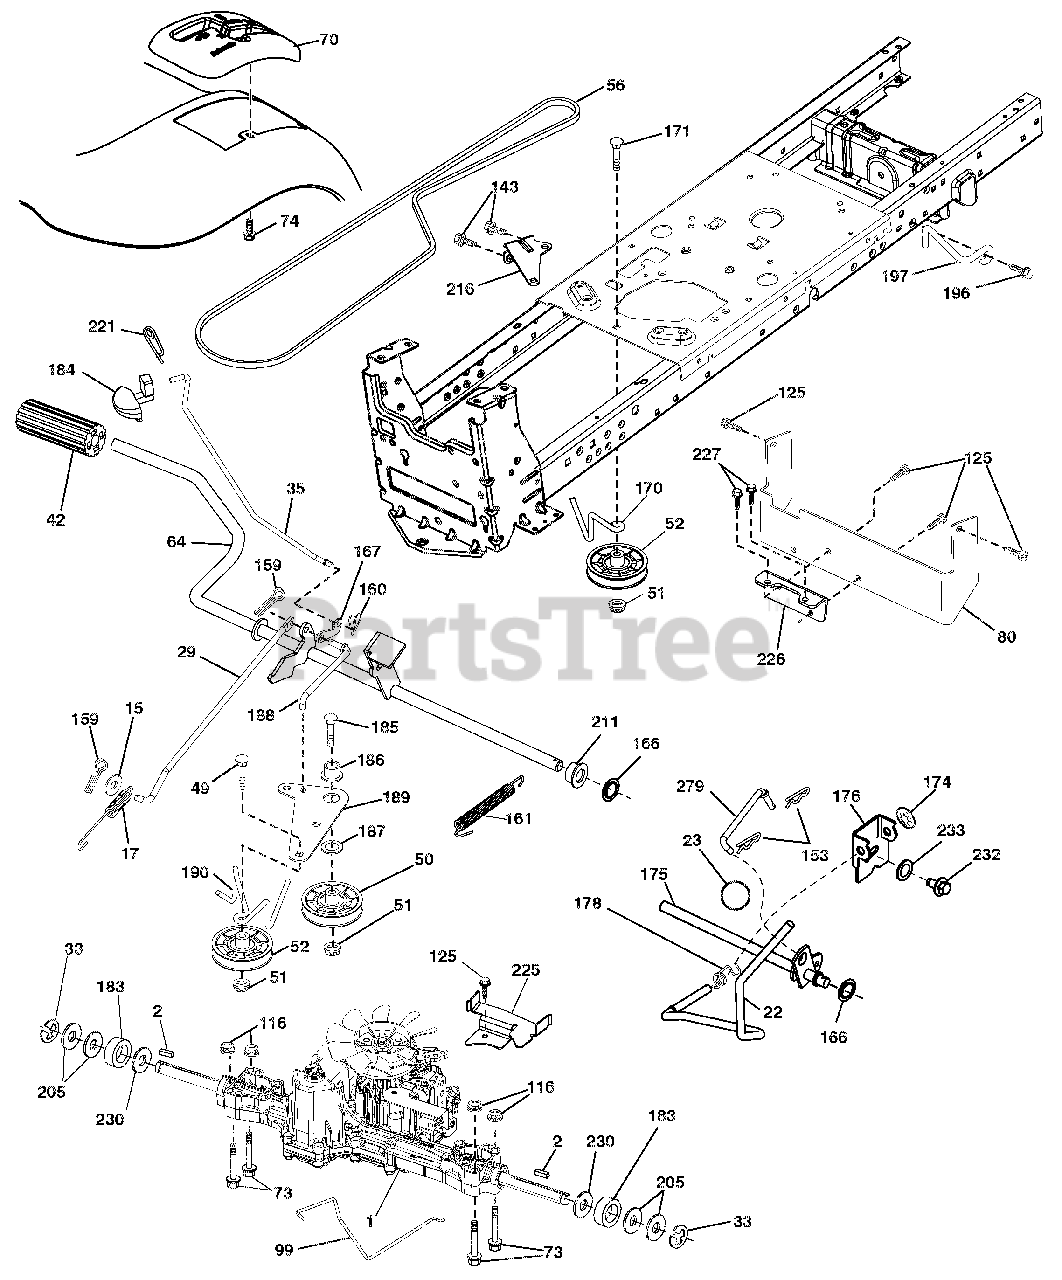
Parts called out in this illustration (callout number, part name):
1	TRANSAXLE, TUFFTORQ K46BA
2	KEY.SQUARE.2.0 X .1845/.1865
15	WASHER.13/32 X 13/16 X 16 GA.
17	SPRING.BRAKE.K46.GREEN
22	ROD.SHIFT.FENDER.TLT.2006
23	KNOB DELUXE
29	ROD.BRAKE.K46
33	E-RING.#5133-75
35	ROD BRAKE PARKING LT TEX
42	COVER PEDAL BLK ROUND
49	BOLT.RDHD.3/8-16UNCX1-3/4.GR5
50	IDLER.FLAT.910"OFFSET
51	Nut, Hex, Flangelock 3/8-16
52	IDLER.V-GROOVE.910"OFFSET
56	V-BELT.MOWER.92.40.42/K46
64	SHAFT ASM.PEDAL.BRAKE CONTROL
70	CONSOLE SHIFT STL HYD BLACK TX
73	BOLT HEX FLGHD 5/16-18 GR.5
74	SCREW.HEX.WSH.HI-LO.1/4X1/2UNC
80	STRAP.TORQUE.K46/18"TEX
99	ROD.SPRING.BYPASS.K46.LT.Z
116	Nut, Lock Hex Flange 5/16-18 u
125	SCREW.5/16-18X3/4.SMGML.TAP/BL
143	SCREW.THDROL.5/16-18 X 1/2TYTT
153	RETAINER SPRING
159	PIN.COTTER.1/8 X 3/4.CAD.
160	RETAINER.CLIP(M).DIA.290
161	SPRING.RETURN.CLUTCH.6.75
166	NUT PUSH .625
167	LATCH.BRAKE.PARKING
170	KEEPER BELT CENTERSPAN
171	BOLT.RD.HD.SQ.NK.3/8-16UNC X 2
174	NUT.PUSH..500
175	SHAFT ARM SHIFT
176	ARM.CLEVIS.ROD.SHIFT
178	SPRING.SHIFT.GT.2006
183	SPACER.AXLE.HYDRO/PEERLES
184	HANDLE.PARKING BRAKE.
185	BOLT.RDHD.3/8-16UNC X2-3/4 GR5
186	SPACER.RETAINER
187	WASHER.13/32 X 2 X 10 GA.
188	LINK.CLUTCH.GROUND DRIVE
189	BELLCRANK.GROUNDRIVE.NSTG/NSTL
190	KEEPER.BELLCRANK.DRIVE.GROUND
196	SCREW.3/8-16X1.SMGML.TAP/R.BLK
197	LINK.CLUTCH.ANTI-ROTATIN.1"CRK
205	WASHER.25/32 X 1-5/8 X 16GA.
211	BUSHING.SHAFT.BRAKE.HAND CONTR
216	BRACKET.PULLEY.IDLER.WTEX
221	RETAINER.SPRING.CLIP.HANDLE
225	KEEPER.BELT.TRANSAXLE.K46
226	BRACKET.MOUNT.TORQUE.K46.TLT
227	SCREW 5/16-18 X 3/4
230	WASHER.HARDEN..793 X 1.637X060
232	BOLT.FIN HEX.7/16-14X1 GR5
233	WASHER.SERRATED
279	LINK SHIFT T/A
